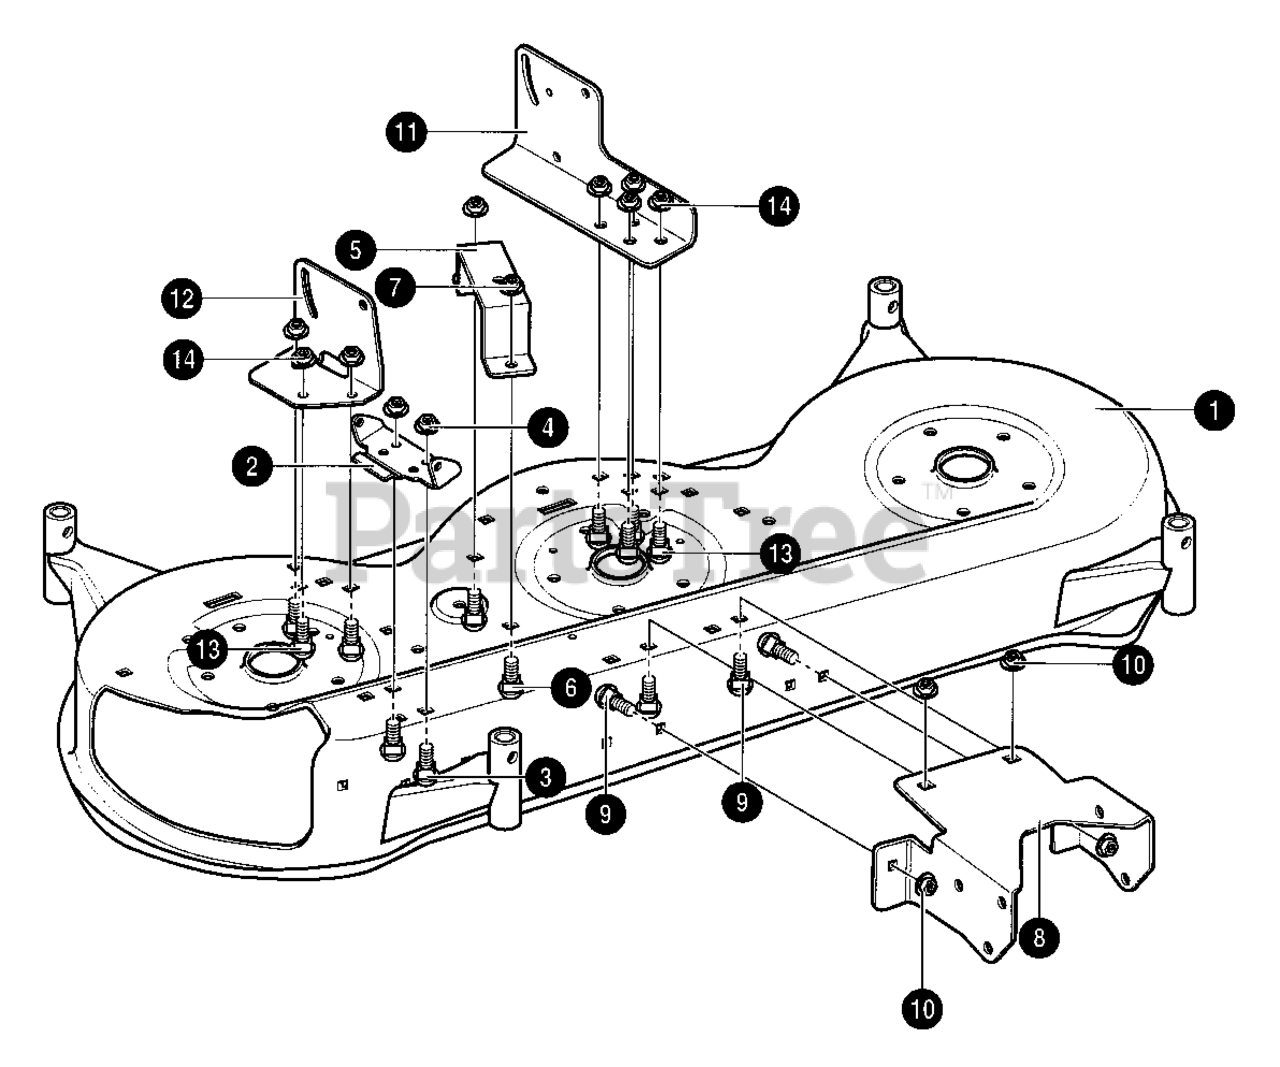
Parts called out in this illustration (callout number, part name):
1	ASSY BLD HSING 42"
2	HINGE, CHUTE BRACKET
3	BOLT, 5/16-18X.63
4	NUT, 5/16-18
5	BRACKET, BELL CRANK
6	BOLT, 5/16-18X.63
7	NUT, 5/16-18
8	BRACKET, FRONT DECK
9	BOLT, 5/16-18X.63
10	NUT, 5/16-18
11	BRACKET, LEFT LIFTER
12	BRACKET, RIGHT LIFTER
13	BOLT, 5/16-18X.63
14	NUT, 5/16-18
